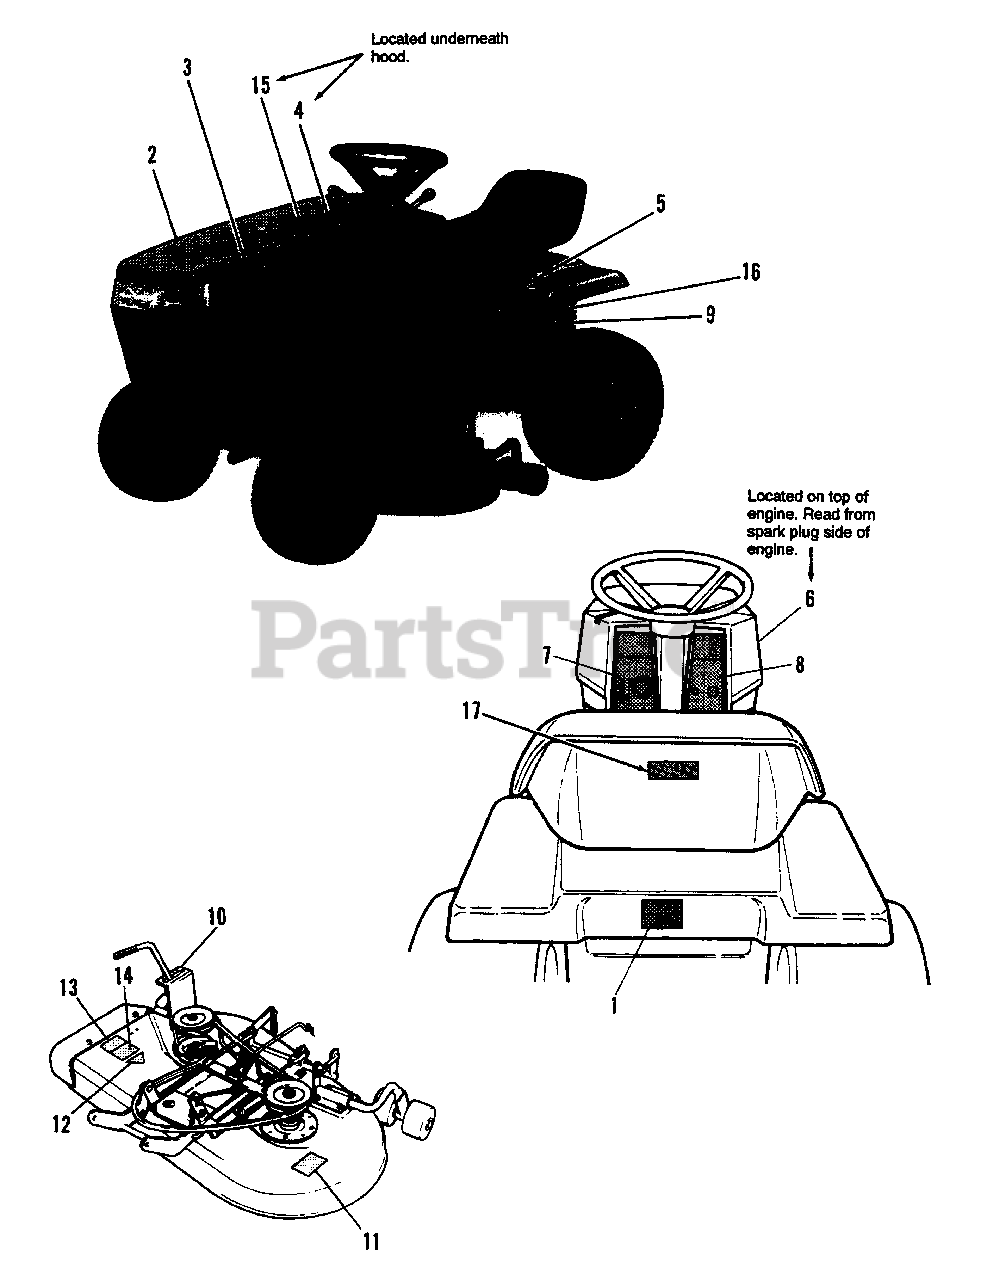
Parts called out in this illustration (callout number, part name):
1	DECAL, AGCO Allis
2	DECAL, Hood, R.H. (Gear models only)
2	DECAL, Hood, R.H. (Hydro models only)
3	DECAL, Hood, L.H. (Gear models only)
4	DECAL, Drive Belt (Gear models only)
5	DECAL, Shift Pattern (Gear models only)
6	DECAL, 12.5 HP, I/C
7	DECAL, Dash, L.H. Side
8	DECAL, Dash, R.H. Side
9	DECAL, Warning, Fan, (Hydro Models only)
10	DECAL, Mower Height
11	DECAL, Danger, Rotating Blade
12	DECAL, OPEI
13	DECAL, Danger, Deflector in Place
14	DECAL, Cutting Width, 36"
15	DECAL, Touch-up Paint
16	DECAL, Tow Valve, (Hydro model, Mfg. No. 1692164)
17	DECAL, USA
